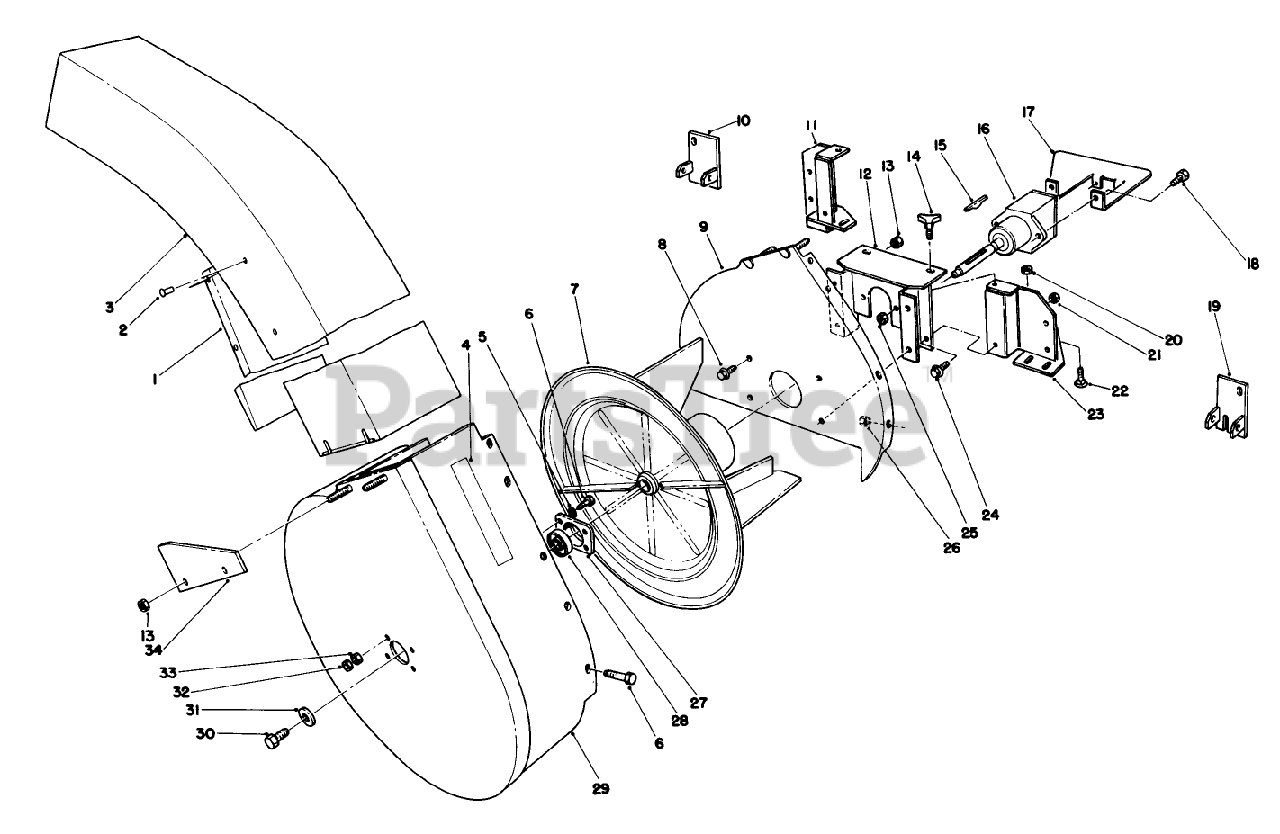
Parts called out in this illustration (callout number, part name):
1	Deflector
3	Chute Assy. (Incl. Ref. #1 & 2)
4	Decal-Waming
5	WASHER-LOCK
6	SCREW-HH
7	Impeller
8	SCREW-HHF
9	Mounting Plate
10	Bracket-Deflector L.H.
11	L/H BLOWER MT/NUT ASM
12	Blower Mount
13	NUT-LOCK, NI
16	Asm-Gear Box
17	Cover-Gear Box
18	SCREW-HH
19	Bracket-Deflector R.H.
20	NUT-KEPS
21	NUT-JAM
22	SCREW-CARR
23	RH BLWR MT BRKT WA
24	SCREW-HHF
25	NUT-LOCK, NI
26	NUT-LOCK, NI
27	CUP-BEARING
28	BEARING-BALL
29	Blower Housing
30	CAPSCREW 3/8 16 3/4
31	SPACER
32	NUT-JAM
33	NUT-HEX
34	Bracket
